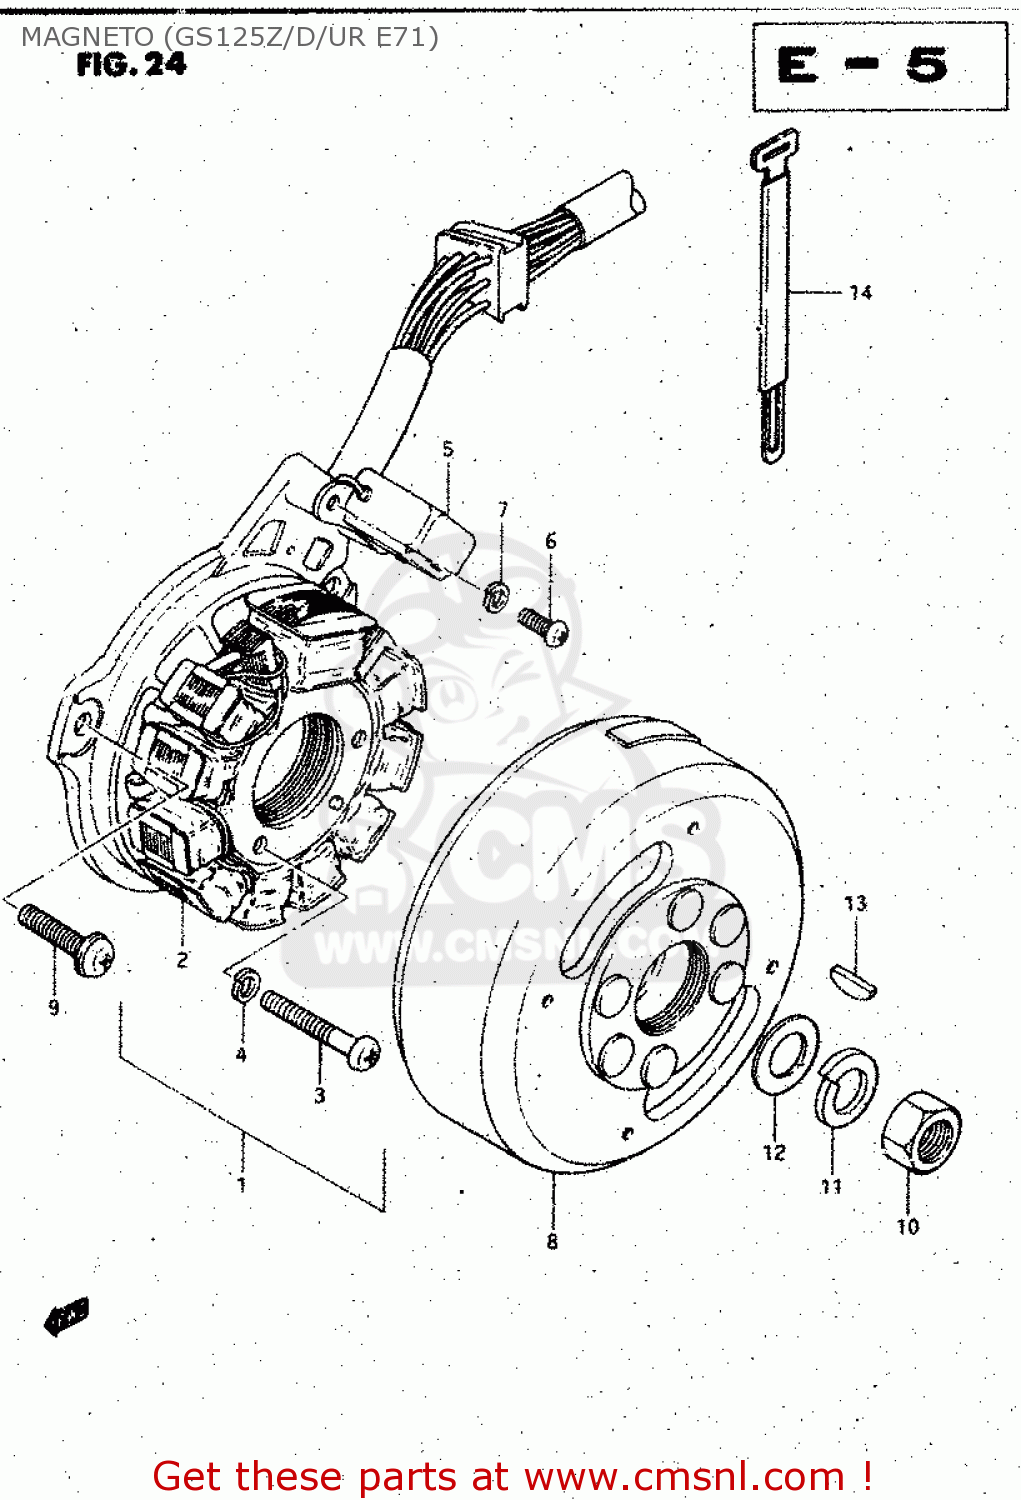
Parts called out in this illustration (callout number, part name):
1	STARTER ASSY
2	COIL,STARTER
3	SCREW
4	WASHER,LOCK
5	COIL,PICK UP
6	SCREW
7	WASHER,LOCK
8	ROTOR ASSY
9	SCREW 5X12
10	NUT
11	WASHER,LOCK,10
12	WASHER
13	KEY
14	CLAMP
